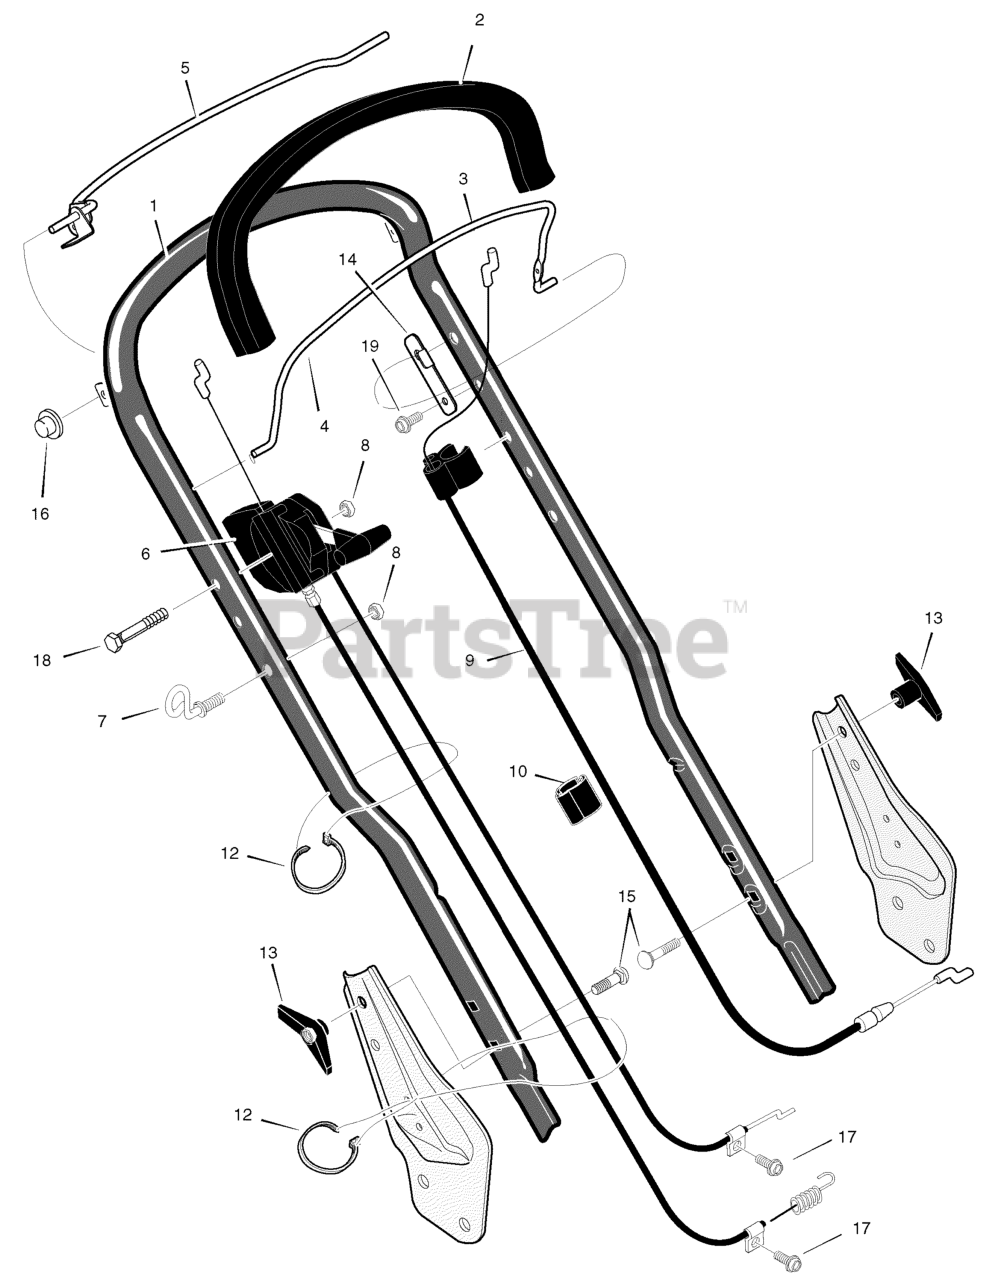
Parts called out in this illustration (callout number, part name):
1	HANDLE, UPPER
2	SLEEVE, HANDLE
3	LEVER, STOP
4	BRACKET, STOP & DRIVE LEVER
5	LEVER, DRIVE
6	DRIVE CONTROL & CABLE
9	CABLE, STOP
10	CLIP, CABLE
12	STRAP, TIE
13	WINGNUT
14	BRACKET, STOP
15	BOLT, CARRIAGE
18	GUIDE, ROPE
